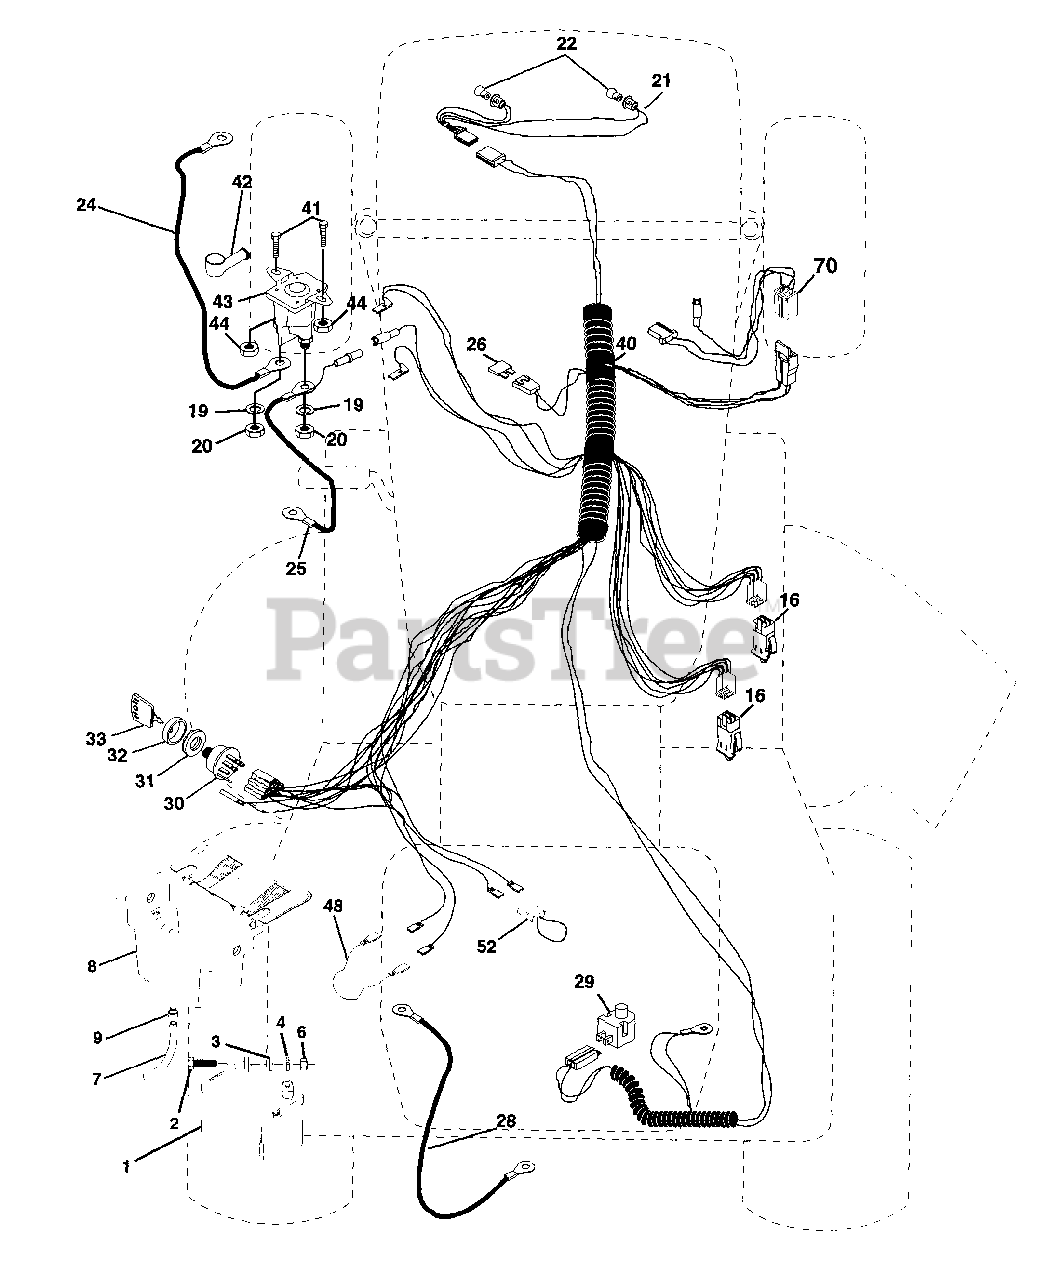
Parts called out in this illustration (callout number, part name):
1	Battery 12 Volt 25 AMP
2	Bolt Hex Hd 1/4-20 unc X 3/4
3	Washer 9/32 X 5/8 X 16 Ga.
4	Washer Lock Hvy Helical 1/4
6	Nut Fin Hex 1/4-20 Unc
7	Tube Plastic 12"
8	Case Battery Mech Hinge
9	Clamp Hose Olive
16	Switch interlock Push-In
19	Washer Lock 1/4
20	Nut Jam Hex 1/4-20 Unc
21	Harness Asm Light W/4152j
22	Bulb Light #1156
24	Cable Battery 6 Ga 11" red
25	Cable Battery 6 Ga 44" red w/16 wire
26	Fuse 30 AMP Auto Green
28	Cable Ground 6 Ga 12" black
29	Switch Plunger Nc Gray
30	Switch Ign 4 pos w/lights
31	Nut Ignition
32	Cover Sw ignition
33	Key Ign Modelled Generic
40	Harness Ign.
41	Bolt Blk Fin Hex 1/4 - 20 x 1/2
42	Cover Terminal Red
43	Solenoid
44	Nut Keps Hex 1/4-20 Unc
48	Adapter Ammeter Rectangular
52	Protection Wire Loop
70	Harness, Eng. B&S/Tec Dual
